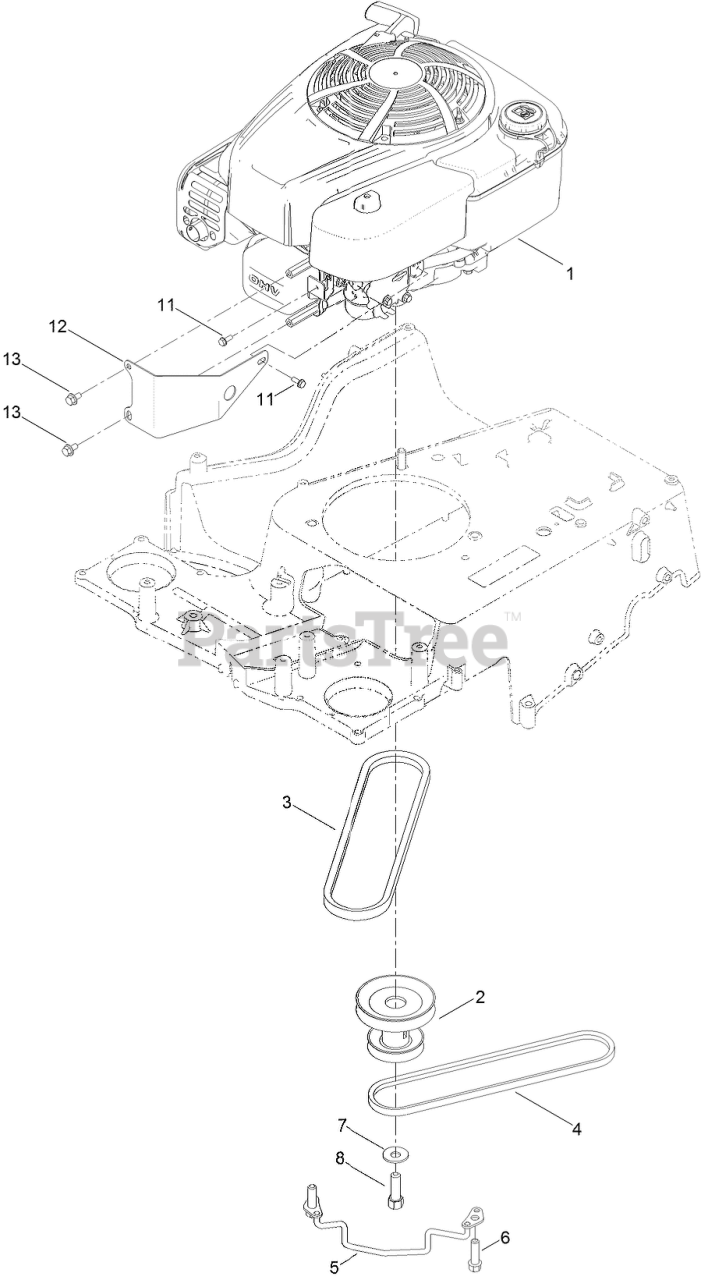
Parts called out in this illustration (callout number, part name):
2	PULLEY-ENGINE
3	V-BELT
4	V-BELT, TRACTION
5	GUIDE-BELT
6	SCREW-TAPTITE
7	WASHER-BELLEVILLE
8	SCREW-HH
11	SCREW-TAPTITE
12	GUARD-ENGINE
13	SCREW-HHF
